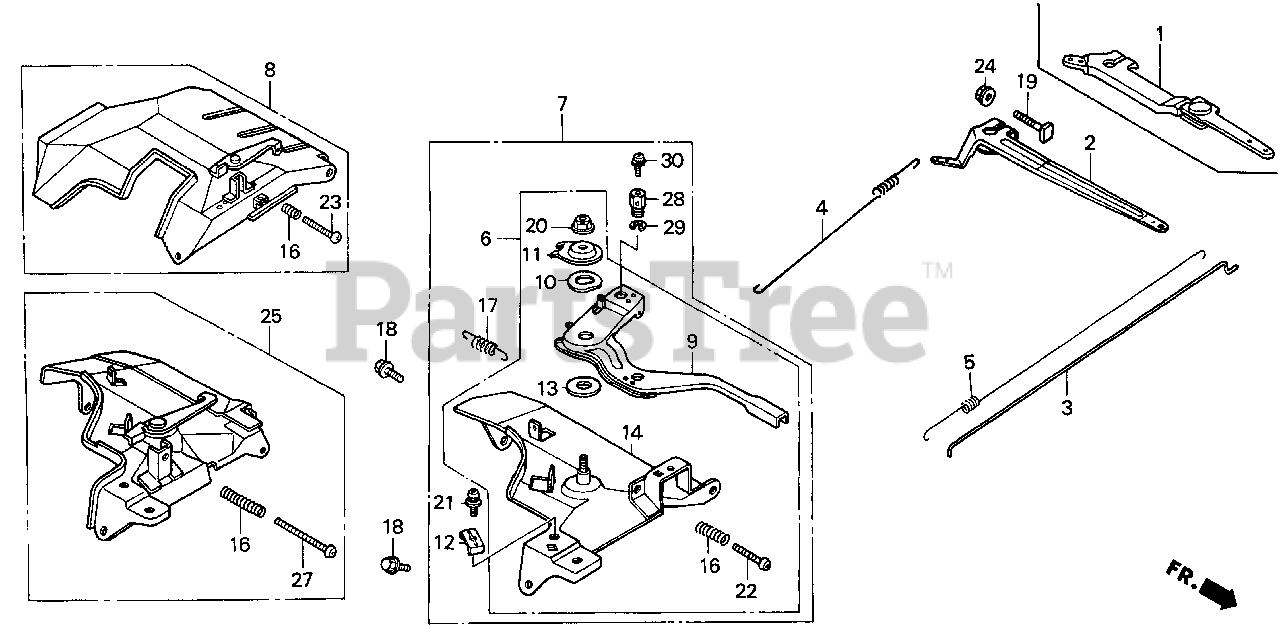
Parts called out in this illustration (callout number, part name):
2	ARM, GOVERNOR
3	ROD, GOVERNOR
4	SPRING, GOVERNOR
5	SPRING, THROTTLE RETURN
7	CONTROL ASSY. (REMOTE)
9	LEVER, CONTROL
10	SPRING, LEVER
11	WASHER, CONTROL LEVER
12	HOLDER, CABLE
13	SPACER, CONTROL LEVER
14	BASE, CONTROL
16	SPRING, CONTROL ADJUSTING
17	SPRING, CABLE RETURN
18	BOLT, FLANGE (6X12) (CT200)
19	BOLT, GOVERNOR ARM
20	NUT, SELF-LOCK (6MM)
21	SCREW, PAN (5X16)
22	SCREW, PAN (5X32)
24	NUT, FLANGE (6MM)
